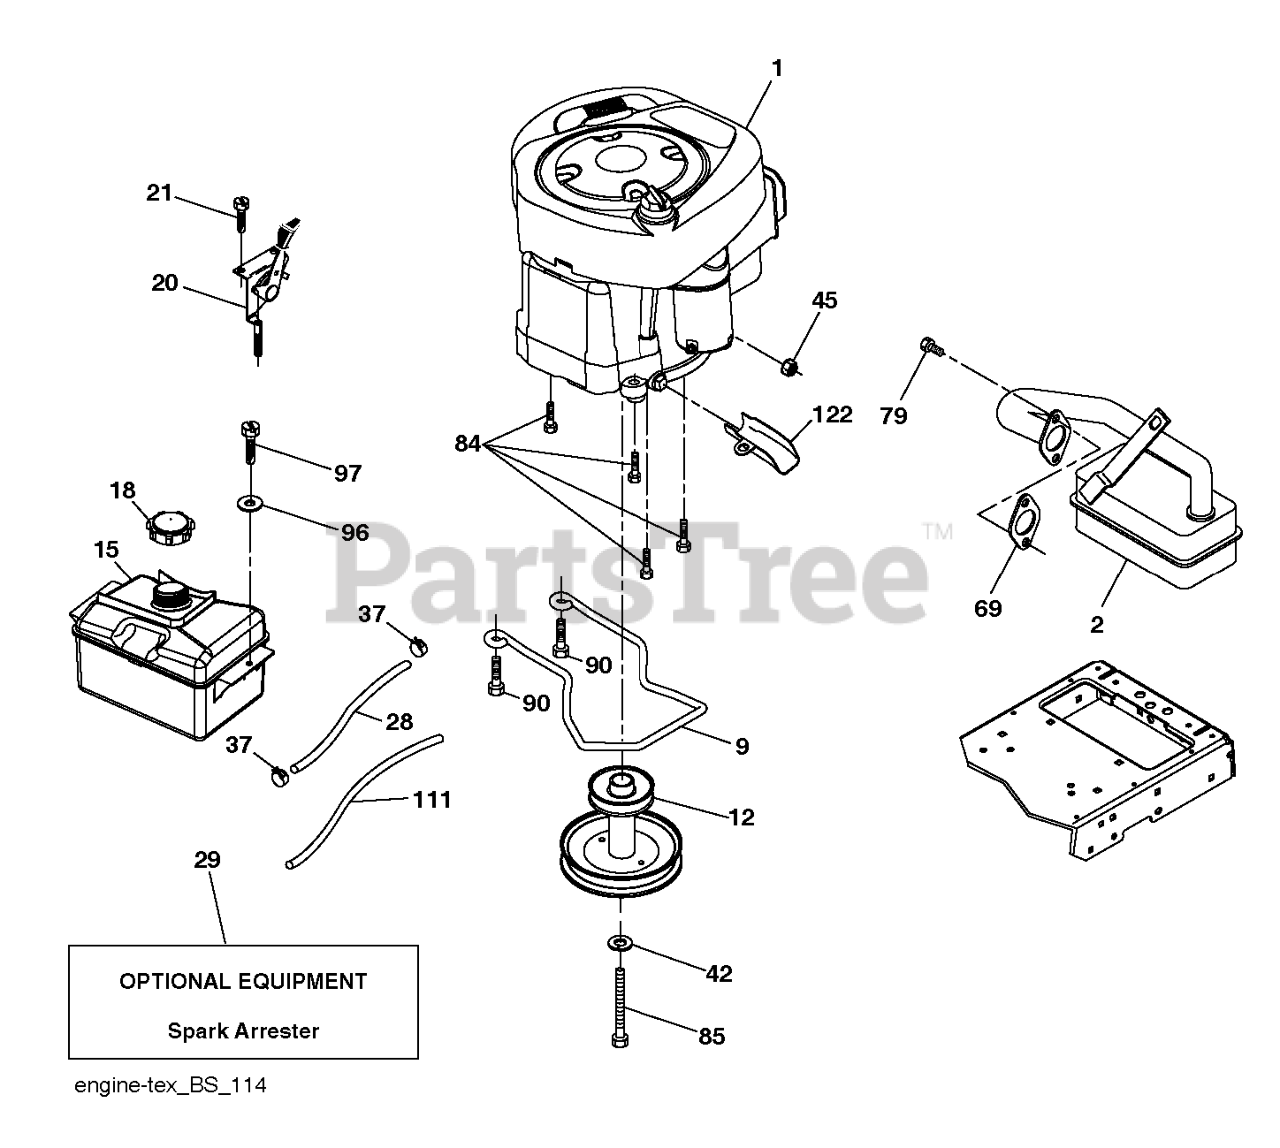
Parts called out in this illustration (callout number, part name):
2	MUFFLER.LT.BRIGGS.14HP.IC/OHV
12	ENGINE.PULLEY
18	CAP.FUEL.2 WAY VENT
20	CONTROL.TH/CK.C.
28	LINE.FUEL.20"FRONT.EMI
29	KIT.SPARK ARRESTOR 794945 B&S
37	HOSE CLAMP
69	REPL BY 532 27 22-93
84	SCREW.3/8-16
85	BOLT.HEX.7/16-20X4.GR5.1.5BLUE
90	SCREW 3/8-16X1
97	SCREW HEXWSHR 1/4-20X3/4
111	TUBE.PURGE.FUEL.1875
122	EXTENSION DRAIN OIL
